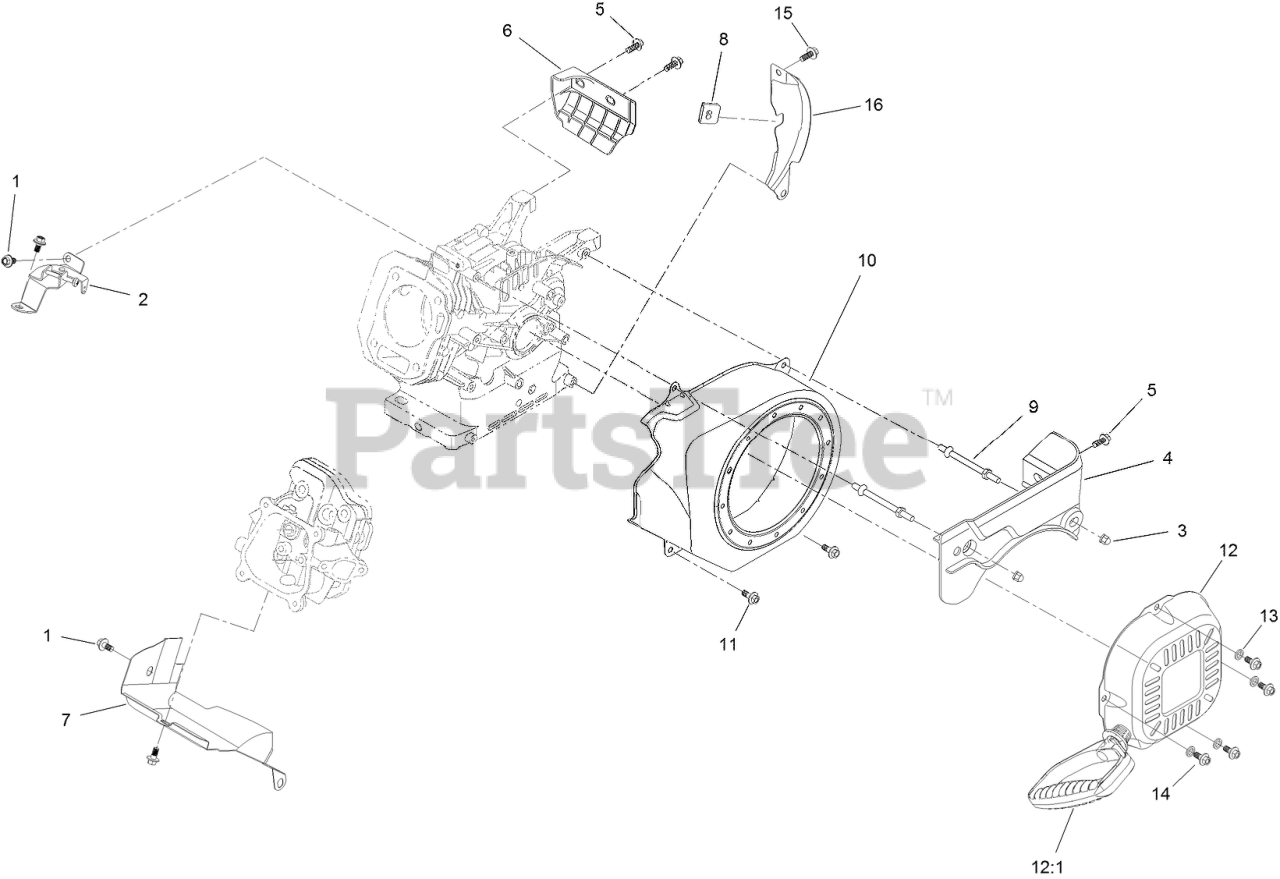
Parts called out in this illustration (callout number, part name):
1	SCREW-HHF
2	SPEED CONTROL ASM
3	NUT-ACORN
4	PANEL-FRONT
5	SCREW-HHF
6	PANEL-SIDE, ENGINE
7	SHROUD-LOWER
8	GROMMET-RUBBER
9	STUD-MOUNT
10	SHROUD-BLOWER
11	SCREW-HHF
12	RECOIL STARTER ASM
12:1	HANDLE-RECOIL
13	WASHER-PLAIN
14	SCREW-HHF
15	SCREW-HHF
16	SHIELD-FLYWHEEL
